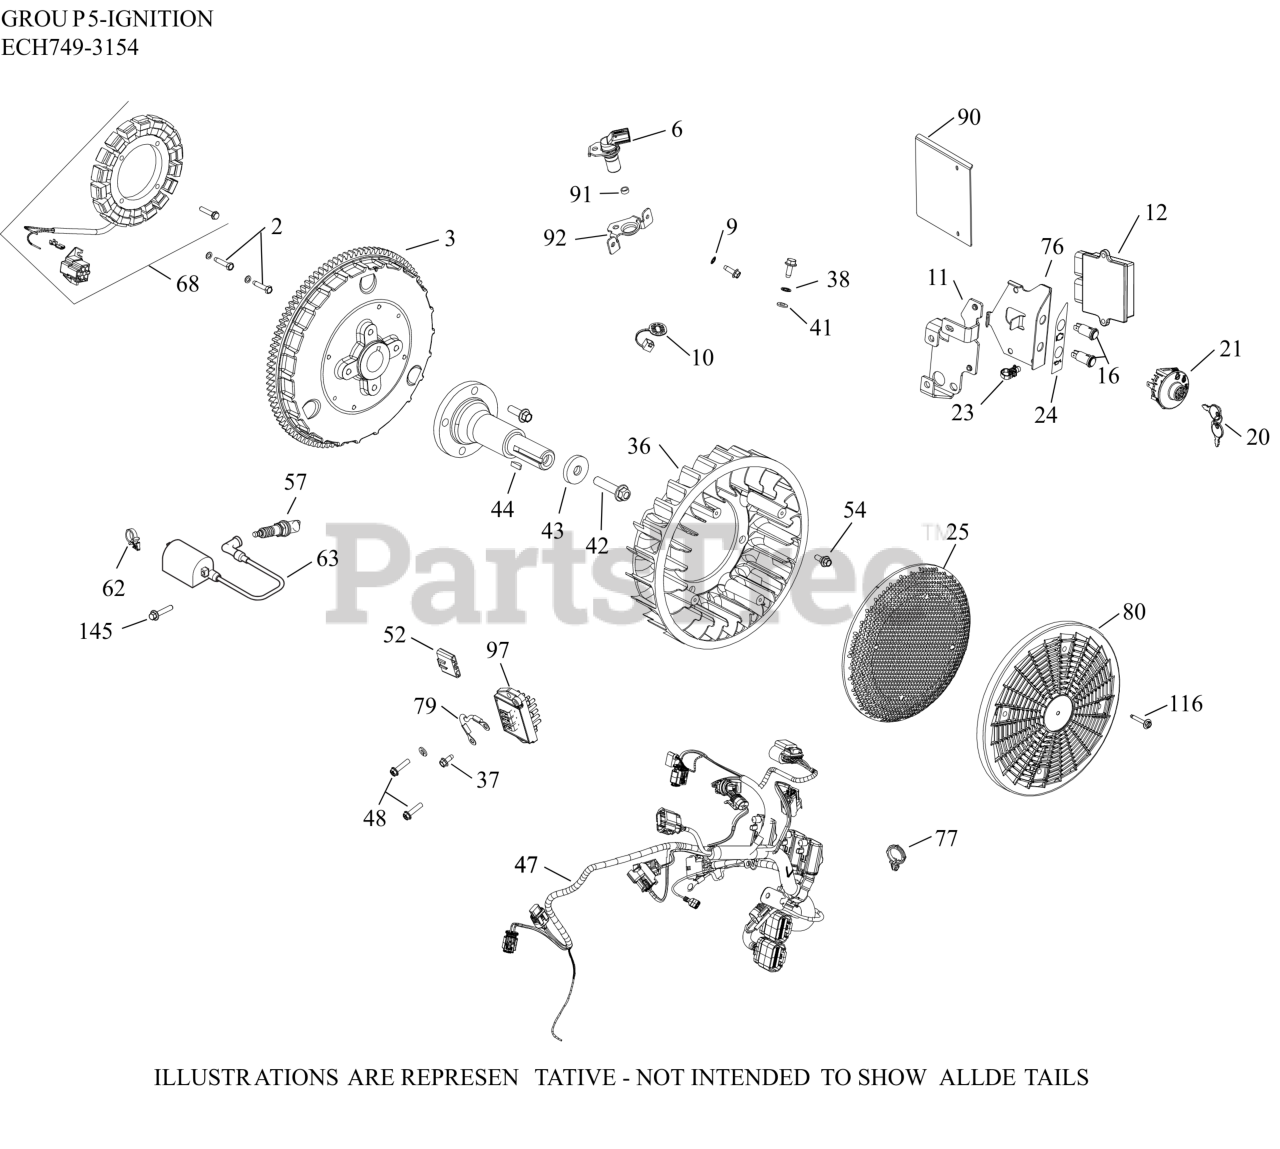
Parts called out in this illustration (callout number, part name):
2	SCREW, THREAD FORMING
3	FLYWHEEL, ASSEMBLY
6	SENSOR, SPEED
9	WASHER, INT TOOTH LOCK #10
10	CAP, CONNECTOR
11	BRACKET, ECU
12	MODULE, ECU ECH749
16	LIGHT, INDICATOR
20	KEY, SET OF 2
21	KIT, KEY SWITCH (SNAP-IN)
23	TIE, WIRE
24	DECAL, WARNING LIGHT
25	KIT GRASS SCREEN
36	FAN-USE 24 755 253-S
37	SCREW, THREAD FORMING
38	WASHER, INT TOOTH LOCK 1/4"
41	WASHER, FLAT 1/4" (O.D. 1/2")
42	SCREW, HEX FLANGE
43	WASHER, FLAT
44	KEY, 3/16" X 5/8"
47	HARNESS, WIRING ASSEMBLY
48	SCREW, HEX FLANGE HI-LO
52	CONNECTOR
54	BOLT, SHOULDER
57	SPARK PLUG, RFI
63	COIL, IGNITION - EFI (RFI/EMC)
68	KIT, 25 AMP STATOR ASSY.
76	BRACKET, WARNING LIGHT
77	RETAINER, WIRE HARNESS
80	SCREEN, GRASS
90	GUARD, ECU
92	BRACKET, SENSOR
97	REGULATOR, RECTIFIER (20-30AMP,FW W/OVP)
116	SCREW, FLG SEMS M4x.7x25
145	SCREW, HEX FLANGE
